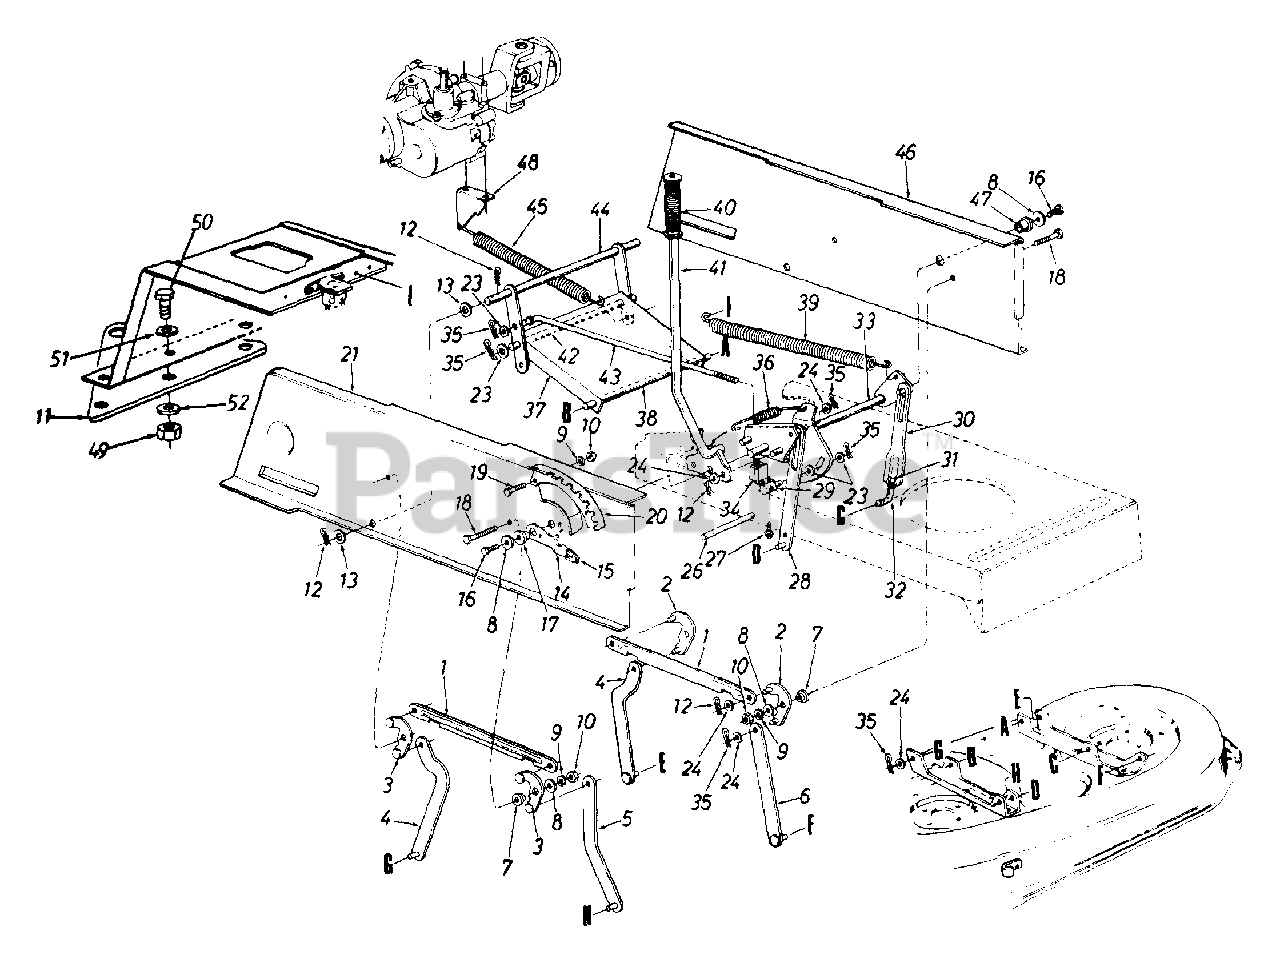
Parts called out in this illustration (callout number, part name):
1	Connecting Rod
2	Pivot Link Ass'y,- L.H.
3	Pivot Link Ass'y.- R.H.
7	Shld. Spacer .318" I.D.
8	Fl-Wash..344" I.D. x 1.125"
9	L-Wash. 5/16" I.D.
10	Hex Nut 5/16-18 Thd.
11	Hitch Plate Extension
12	Cotter Pin 1/8" Dia.
13	Fl-Wash..635" I.D. x 1.0" O.D.
14	Deck Lift - Down Stop
15	Knob
16	Hex Wash. TT-Tap Scr. 5/16-18 x .75" Lg.
17	Flange Brg..63" I.D.
18	Hex Wash. TT-Tap Scr. 5/16-18 x .875" Lg.
19	Hex Bolt 5/16-18 x .75" Lg.
20	Index Brkt.
21	Upper Frame - R.H.
23	Fl-Wash..385" I.D. x .87" O.D.
24	Fl-Wash..531" I.D. x .93" O.D.
26	Running Board Rod
27	Truss Mach. Scr. 410 x .5" Lg.
31	Hex Nut 1/2-20 Thd. (Gr. 5)
32	Lift Link Adjuster
33	Lift Shaft Ass'y.
34	Safety Switch (Deck)
35	Inter. Cotter Pin 3/8" Dia.
36	Extension Spring
37	Stabilizer Bracket
38	Shaft 1/2" Dia. x 10.28" Lg.
39	Extension Spring
40	Grip (Lift Handle)
41	Deck Lift Handle Ass'y.
42	Shaft 3/8" Dia. x 9.34" Lg.
43	Disengagement Rod
44	Stabilizer Shaft Ass'y.
45	Extension Spring 7.58" Lg.
46	Upper Frame - L.H.
47	Flange Brg..632" 1.0.
49	Hex Nut 7/16-14 Thd. (Gr. 5)
50	Hex Bolt 7/16-14 x 1" Lg.
51	Bell-Wash. .46" I.D.
52	Fl-Wash. .469" 1.D. x 1.13" O.D.
